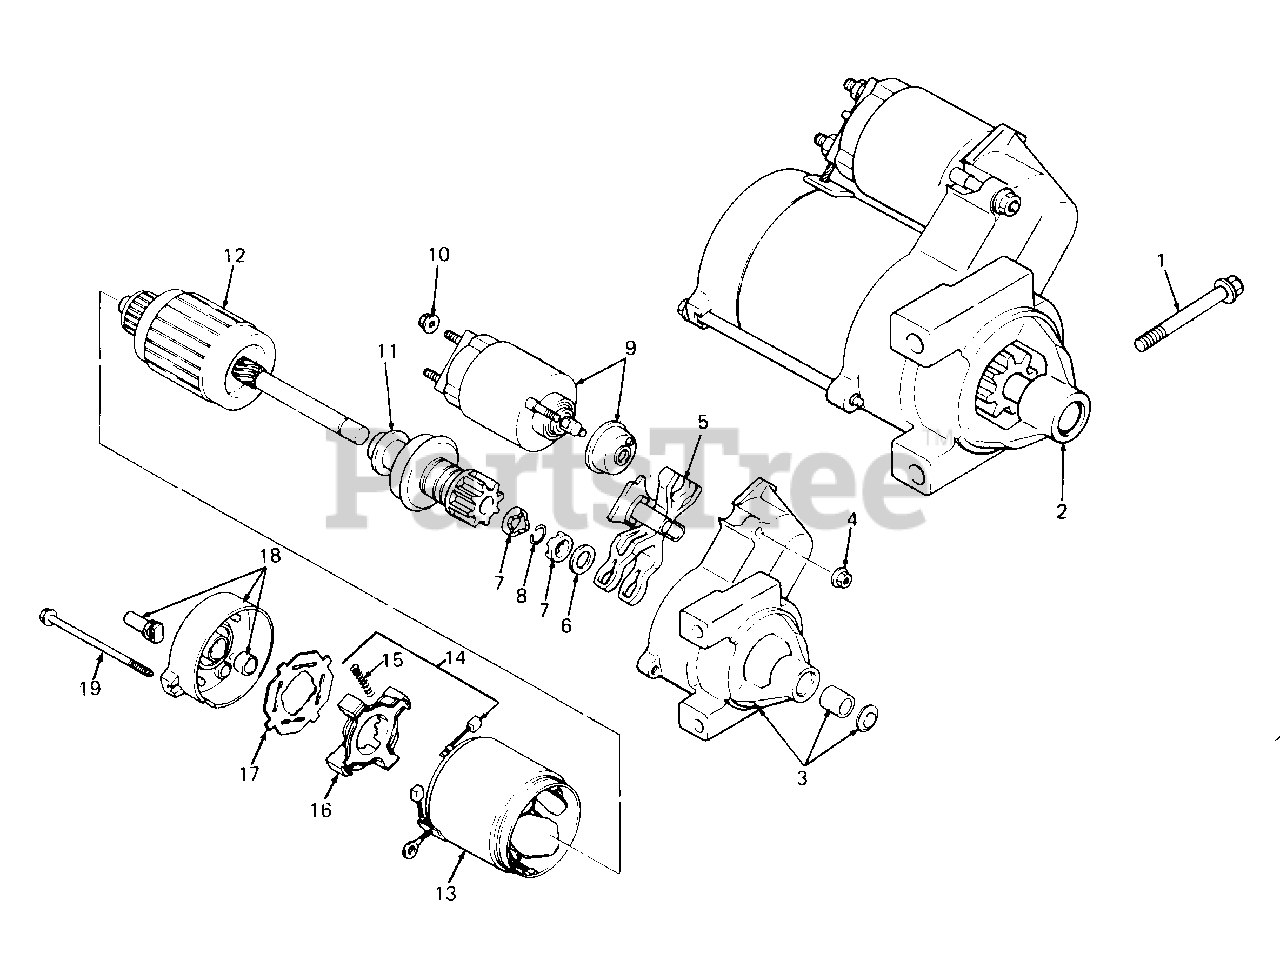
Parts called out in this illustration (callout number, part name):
1	Screw, M8 X 1.25 X 80.6
2	Starter Assy, Solenoid Shift
3	Cap, Drive End
4	Nut, Starter
5	Lever, Starter Drive
6	Washer, Thrust
7	Nut, Stop Collar
8	Ring, Retainer
11	Drive, Pinion
14	Kit, Brush
15	Spring, Brush
16	Holder, Brush
18	Cap, Commutator End
